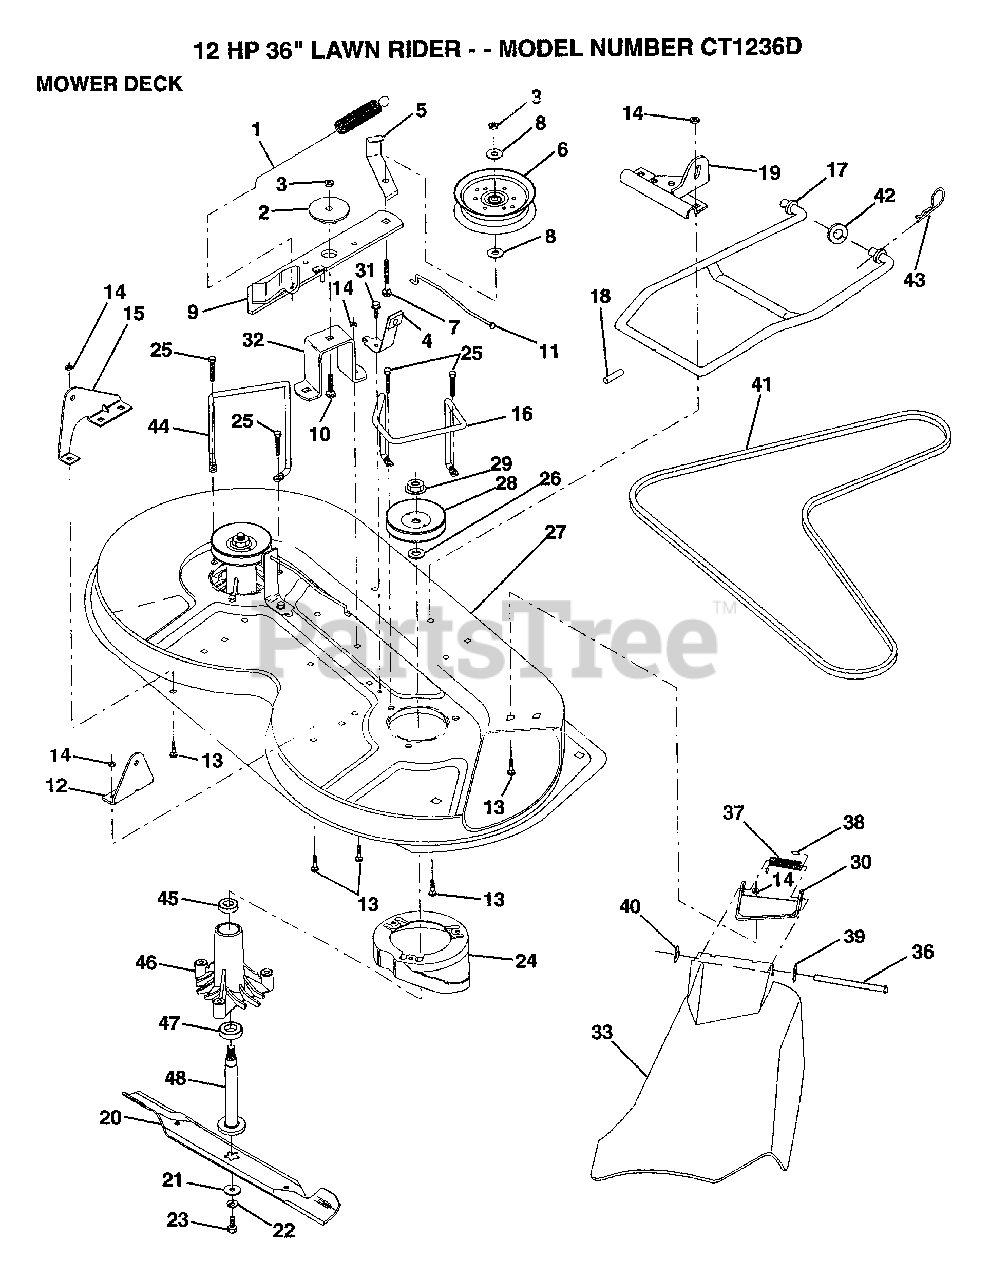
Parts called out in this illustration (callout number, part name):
2	SPACER RETAINER
4	BRAKE ASM
5	IDLER BELT GUIDE
6	PULLEY IDLER
7	BOLT
8	WASHER
10	BOLT D
11	BRAKE ROD
12	"BRKT,LIFT REAR"
13	BOLT
15	"BRKT,LIFT REAR LH"
17	MOWER LINK STAB
18	"PIN,GROOVE"
19	"BRKT,LINK STABILI"
21	WASHER BLADE
23	BLADE BOLT
26	WASHER
31	SCREW LT
32	"SUPT,IDLER ARM"
36	HINGE ROD
37	SPRING TORSION
38	CAP-SLEEVE LT
39	WASHER
40	NUT PUSH M
41	V-BELT.PRIM.78.5.
43	RETAINER.SPRING
45	BEARING
46	MANDREL ASM
47	BEARING.BALL
